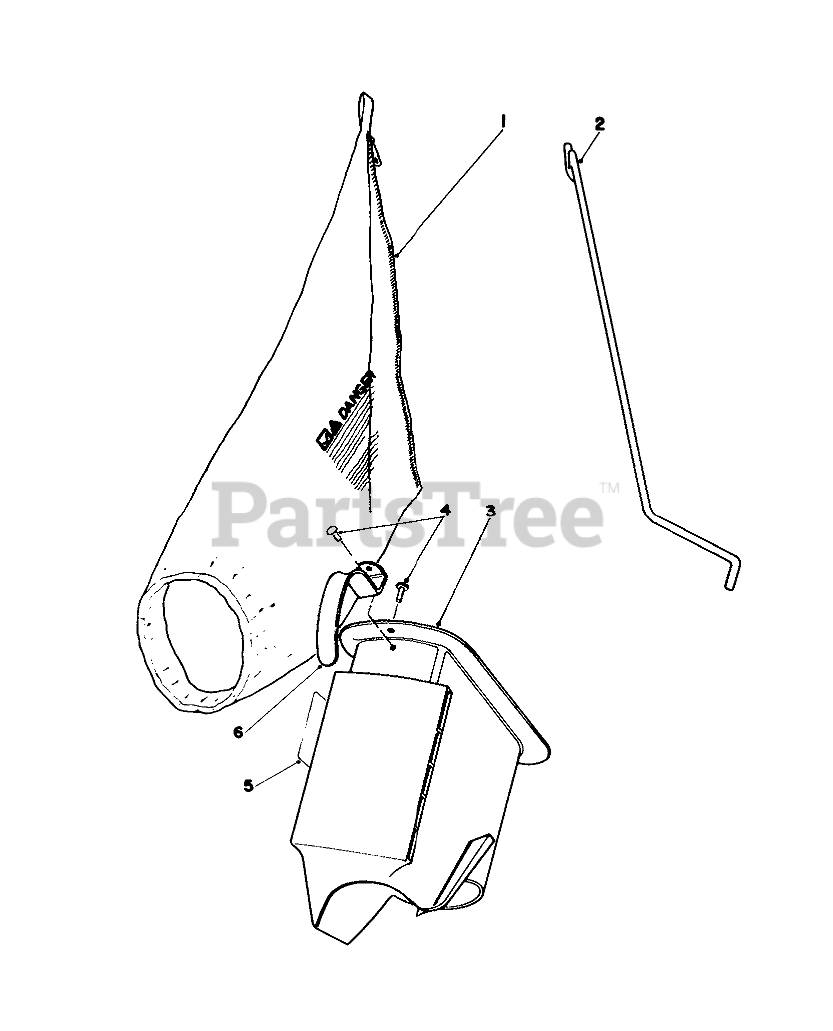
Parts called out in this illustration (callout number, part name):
1	BAG REPLACMNT44-0540
2	BAG ROD
3	Grass Chute (Incl. Ref. #4&6)
4	RIVET 3/16 X 7/16
5	BAG CHUTE DECAL
6	HANDLE-GRASS CHUTE
